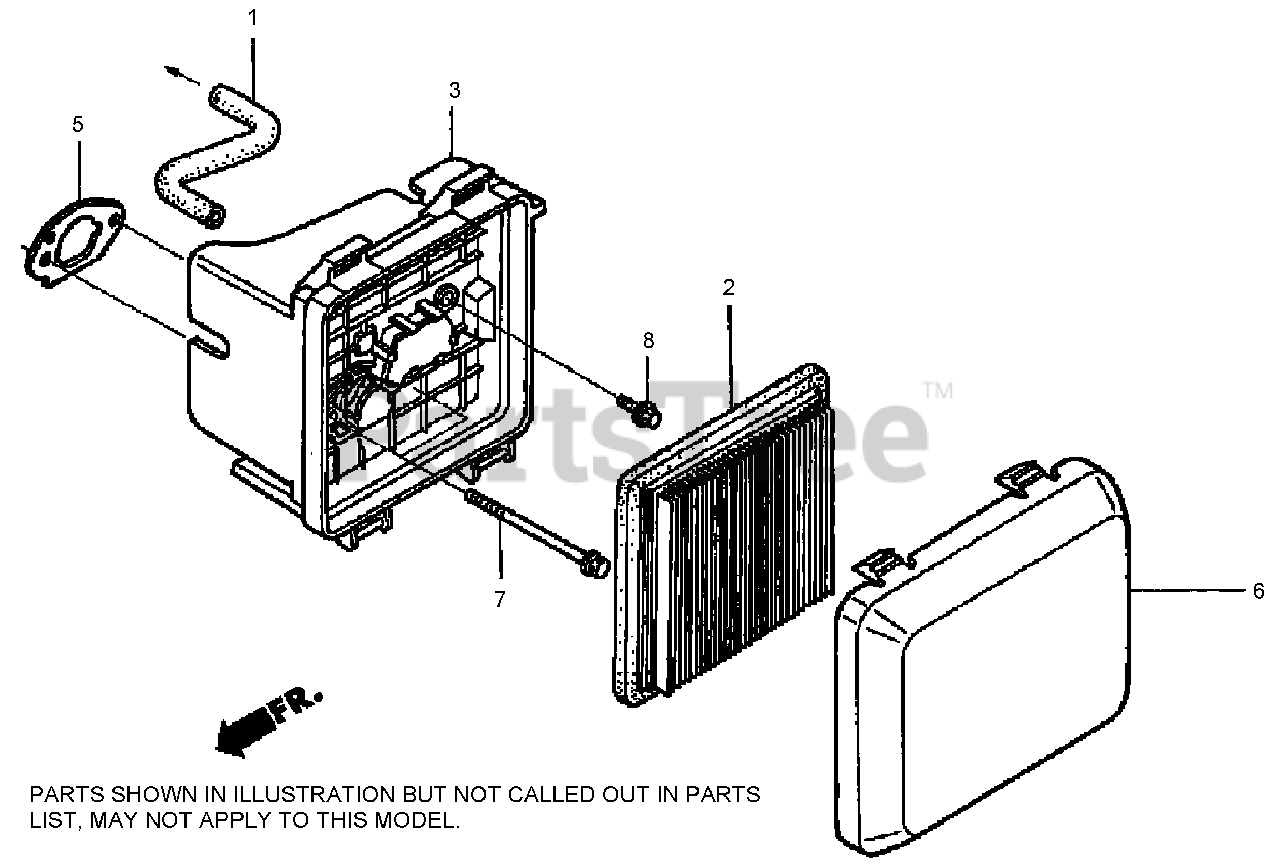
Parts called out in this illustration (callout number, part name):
1	TUBE, BREATHER
2	ELEMENT, AIR CLEANER
3	CASE ASM., AIR CLEANER
5	GASKET, AIR CLEANER
6	COVER, AIR CLEANER
7	BOLT, FLANGE (6X86) (CT200)
8	BOLT, FLANGE (6X14)
